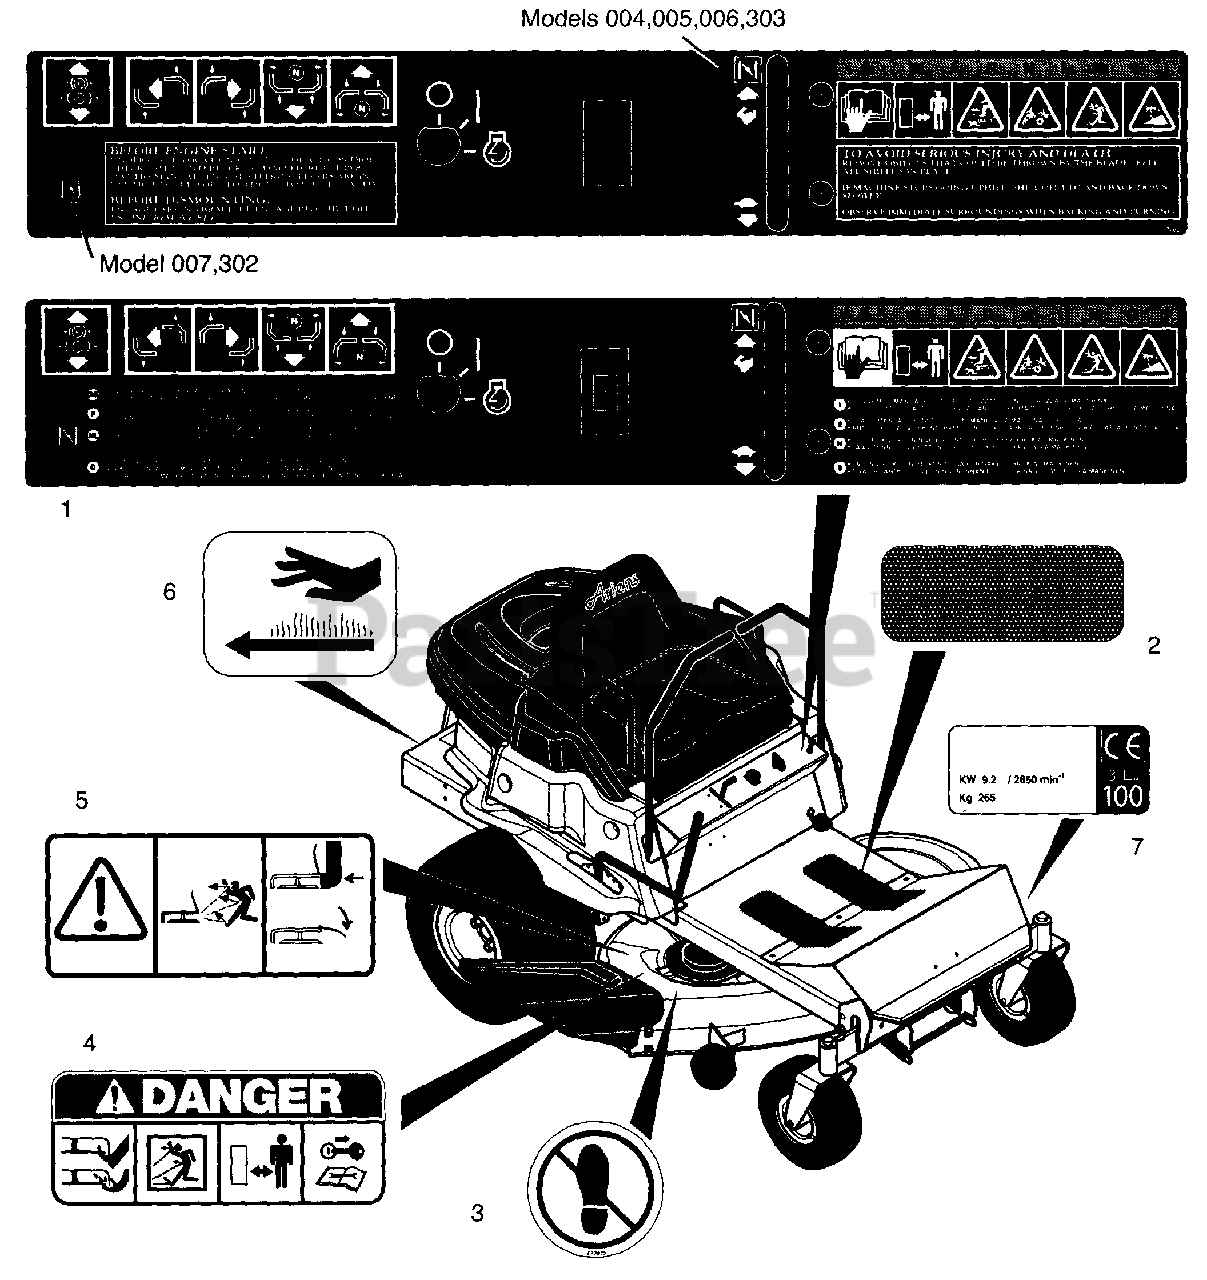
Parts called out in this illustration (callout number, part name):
1	DECAL EZR CONTROL - EXPORT
2	NONSKID COVER
3	NO STEP DECAL
4	DECAL- MOWER PAN
5	DECAL- DISCHARGE
6	DECAL- HOT SURFACE SYMB.
7	S/N COMPLIANCE LABEL EZR
